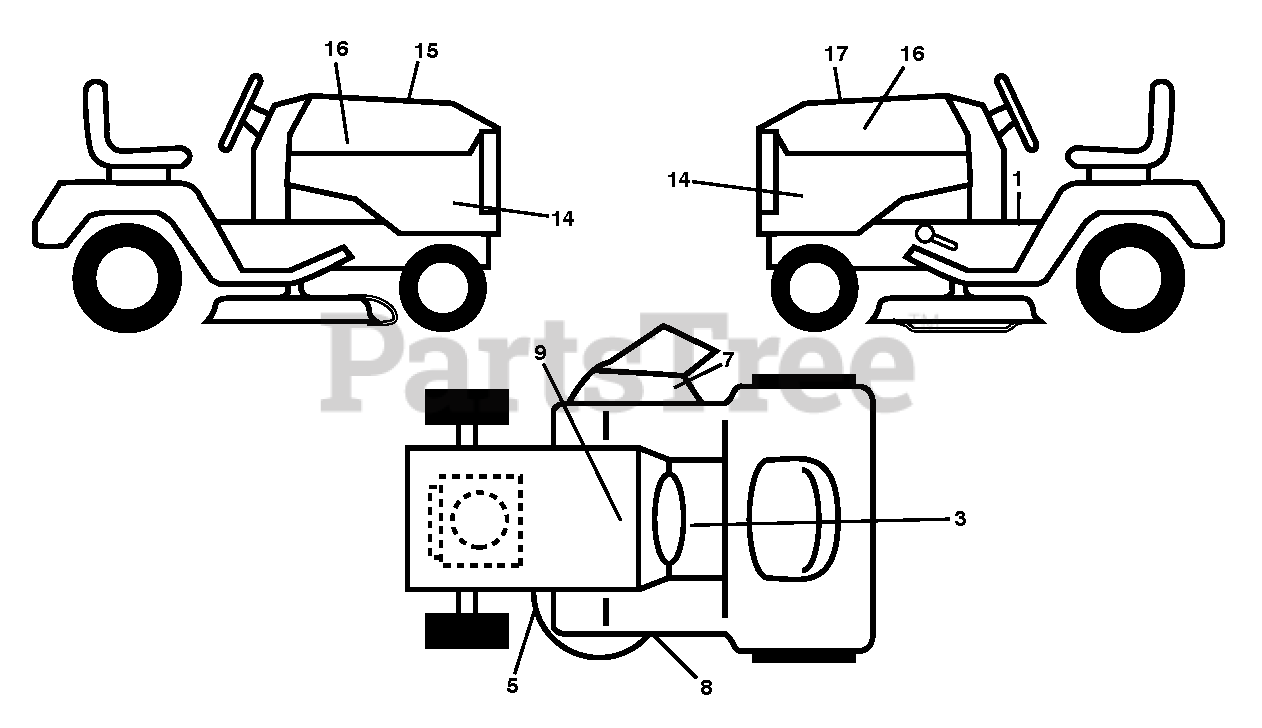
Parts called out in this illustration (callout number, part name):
1	DECAL.FENDER.WARNING.ENG
5	DECAL.MOWER
7	DECAL.WARN.KEEP.HAND.AWAY
8	DECAL.MOWER.SCH.48/54
9	DECAL BTRY SYMBOLS
14	DECAL.SDPNL.YTH22K48.SET.GTII
15	DECAL.WARNING.CUST.RESP.E85.
16	RP.DECAL.BADGE.170MM.TEXTLOGO
